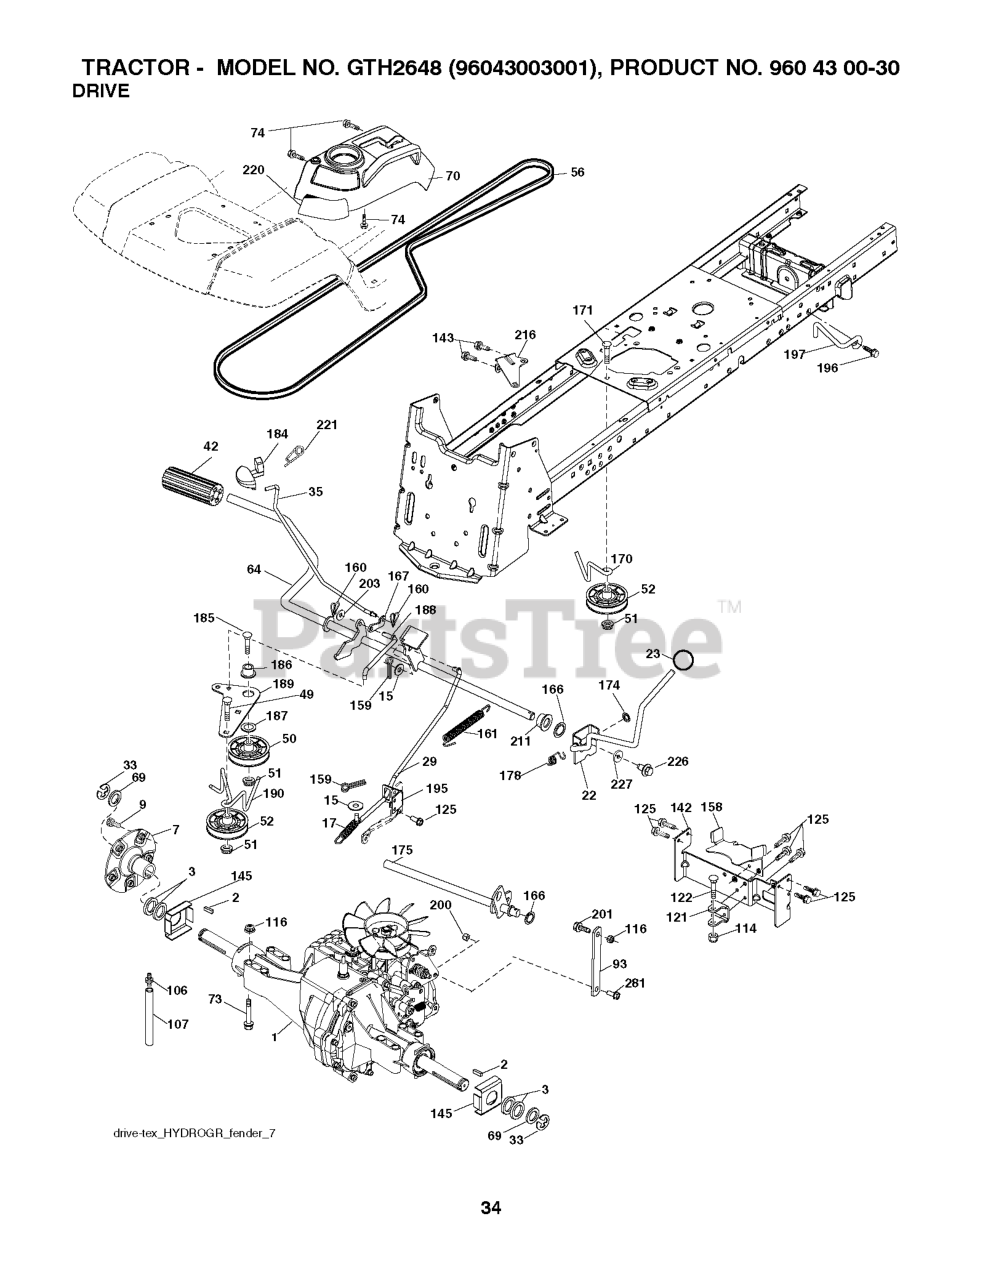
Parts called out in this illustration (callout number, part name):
2	KEY 1/4 X 2.5
7	HUB.ASM.WHEEL.REAR.23"TEX
15	WASHER
17	SPRING.BRAKE.HG3000/3500
22	SHIFTER.ASM.GT.TEX.2006
23	KNOB.DELUXE.(PISTOL.GRIP).BLAC
29	ROD.BRAKE.HG3000/3500
33	E RING HYT
35	ROD.BRAKE.PARKING.GT.H
42	PEDAL COVER T
50	IDLER.FLAT.910.OFFSET
51	NUT LOCK FLG 3/8-16 UNC
52	IDLER.V-GROOVE.910.OFFSET
56	BELT.V.GROUND.DRIVE
64	SHAFT.ASM.PEDAL.BRAKE.
70	RP CONSOLE.ASM.HYDO.HUSQ.
73	BOLT HEX FLGHD 5/16-18X3 GR. 5
74	SCREW.HI-LO.CONSOLE
93	LINK.TRANSAXLE.HG3000/3500
106	CAP, VENT ASSY
114	NUT.71038.31-18.HEX.NYLOCK
116	NUT LOCK HEX FLANGE 5/16-18
121	BRACKET STRAP TORQUE
122	BOLT.5/16-18X2.5
125	SCREW
142	STRAP.TORQUE.HG3000/K46
143	Screw 5/16-18 x 1/2 Hex, Self Tapping 5/16-18 x 1/2
145	WASHER.AXLE.FLANGE.HG-3000
158	KEEPER BELT
159	COTTER PIN
160	RETAINER CLIP
161	SPRING, RETURN LT
166	NUT.PUSH.625.2006
167	LATCH.BRAKE.SPRING
170	KEEPER.V-IDLER.CENTER.
174	NUT.PUSH.500.2006
175	SHAFT ASM SHIFT
178	SPRING.SHIFT.GT2006
184	HANDLE.PARKG.BRK.HUSQ X667
186	SPACER.RETAINER
187	WASHER 12/32X2X10GA
188	RP.LINK.CLUTCH.GROUND.DRIVE
189	BELLCRANK.GROUND.DRIVE.TEX.
190	KEEPER.BELLCRANK.DRIVE
195	RETAINER.ROD.BRAKE.HG3000.TEX
196	SCREW 3/8-16X1
197	BRKT.ANIT-ROTATION.CLUTCH
200	NUT.CENTERLOCK.5/16-
201	BOLT SHOULDER 5/16-18 UNC
203	WASHER
211	BUSHING.SHAFT.BRAKE.HAND
216	BRACKET.PULLEY.IDLER.W/TEX
220	REFLECTOR.RH.TEX GT
221	RETAINER.SPRING.CLIP.H
226	BOLT FIN HEX 7/16-14 X 1
227	WASHER SERRATED
281	Shoulder Bolt
